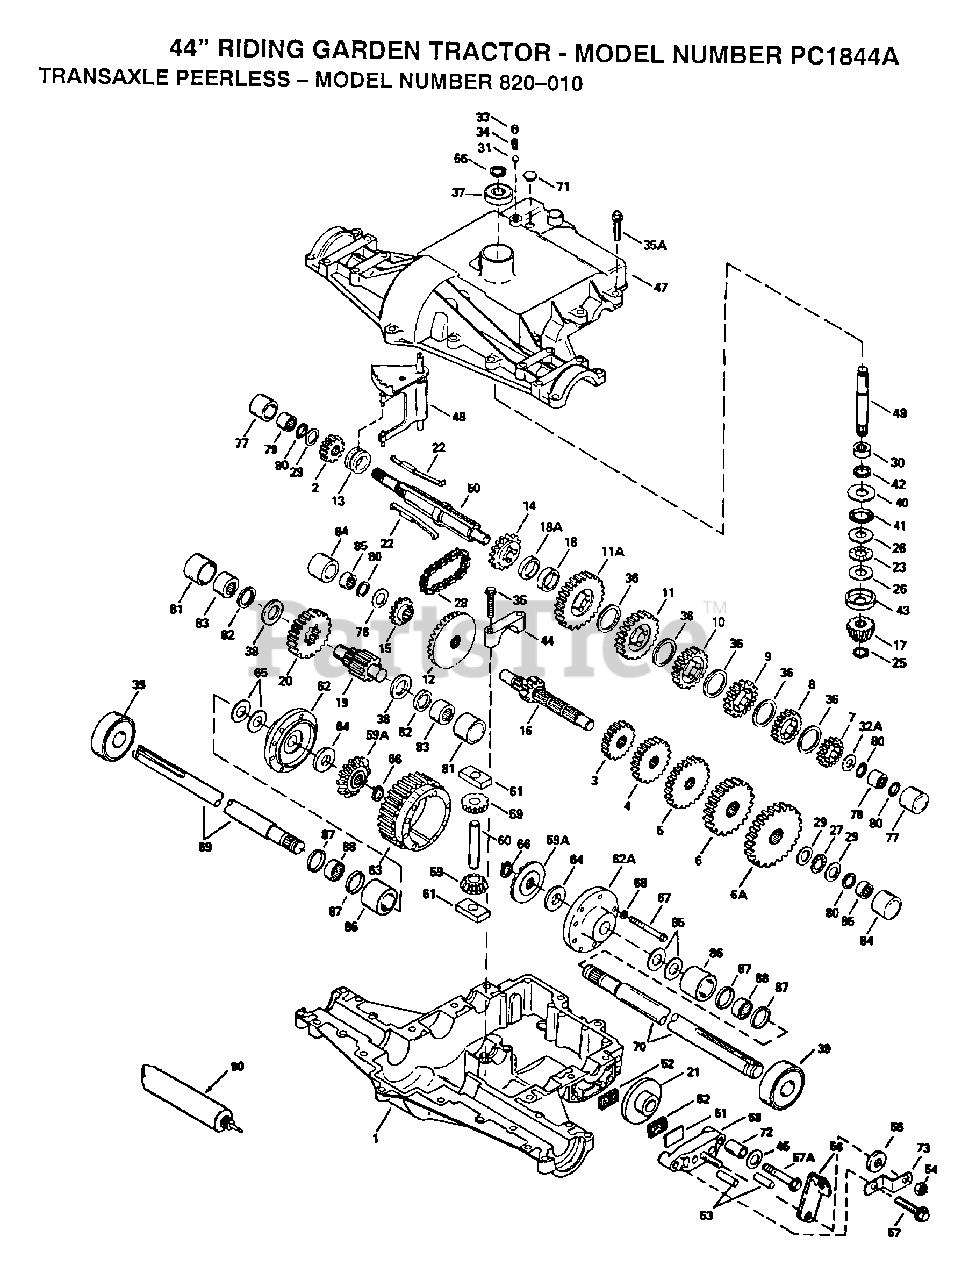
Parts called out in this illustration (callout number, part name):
1	CASE TRANSAXLE
2	GEAR, SPUR, 15T
3	GEAR, SPUR, 12 TEETH
4	GEAR, SPUR, 15T
5	GEAR, SPUR, 20T
6	GEAR, SPUR, 28T
6A	GEAR, SPUR, 31T
7	GEAR, SPUR, 19 TEETH
8	GEAR, SPUR, 22T
9	GEAR, SPUR, 30T
10	GEAR, SPUR, 35T
11	GEAR, SPUR, 37 TEETH
11A	GEAR, SPUR, 41T
12	GEAR BEVEL, 33T
13	COLLAR SHIFT
14	SPROCKET 18T (REV)
15	SPROCKET 9T
16	SHAFT COUNTER
17	BEVEL PINION, INPUT
18	SPACER, .350/.340 THICK
18A	SPACER, .276/.268 THICK
19	SHAFT, OUTPUT
20	GEAR, OUTPUT, 35T
23	BEARING THRUST
25	RETAINING RING
26	WASHER THRUST
27	THRUST BEARING
28	CHAIN, ROLLER
29	WASHER THRUST
30	BEARING NEEDLE
32A	WASHER, THRUST
33	SCREW, 3/8-16 X 3/8"
35	SCREW, 1/4-20 X 1-1/4
35A	SCREW HEX HD 5/16-18 X 1-1/4
36	WASHER THRUST
37	BEARING BALL
38	WASHER THRUST
39	BEARING BALL
42	OIL SEAL 3/4
43	WASHER CUPPED
44	BEARING CAP
45	WASHER FLAT
47	COVER TRANSAXLE
48	ROD AND FORK ASSY SHIFT
49	SHAFT INPUT
50	SHAFT BRAKE
51	PLATE BRAKE PAD
54	LOCKNUT 5/16-24
55	WASHER, FLAT
56	LEVER BRAKE
57	SCREW, 1/4-20 X 1-1/4
57A	SCREW FLNG HEX 1/4-20 X 2-1/4
58	HOLDER BRAKE PAD
59	PINION, 10T
61	BLOCK DRIVE
62	CARRIER DIFF THREADED HOLES
62A	CARRIER DIFF
63	GEAR, RING, 31T
65	WASHER THRUST
67	SCREW, 1/4-20 X 2-1/4
68	WASHER LOCK 1/4
69	AXLE, 12-5/16" LONG
70	AXLE, 16-3/16" LONG
71	PLUG, THRDED, 9/16-18
73	BRKT BRAKE LEVER
78	BEARING NEEDLE
79	BEARING NEEDLE
81	SLEEVE STEPPED
82	RING SQ CUT
83	BEARING NEEDLE CAPPED
84	SLEEVE STEPPED
85	BEARING NEEDLE CAPPED
86	SLEEVE STEPPED
87	RING SQ CUT
88	BEARING NEEDLE
90	GREASE BENTONITE, 32 OZ.
